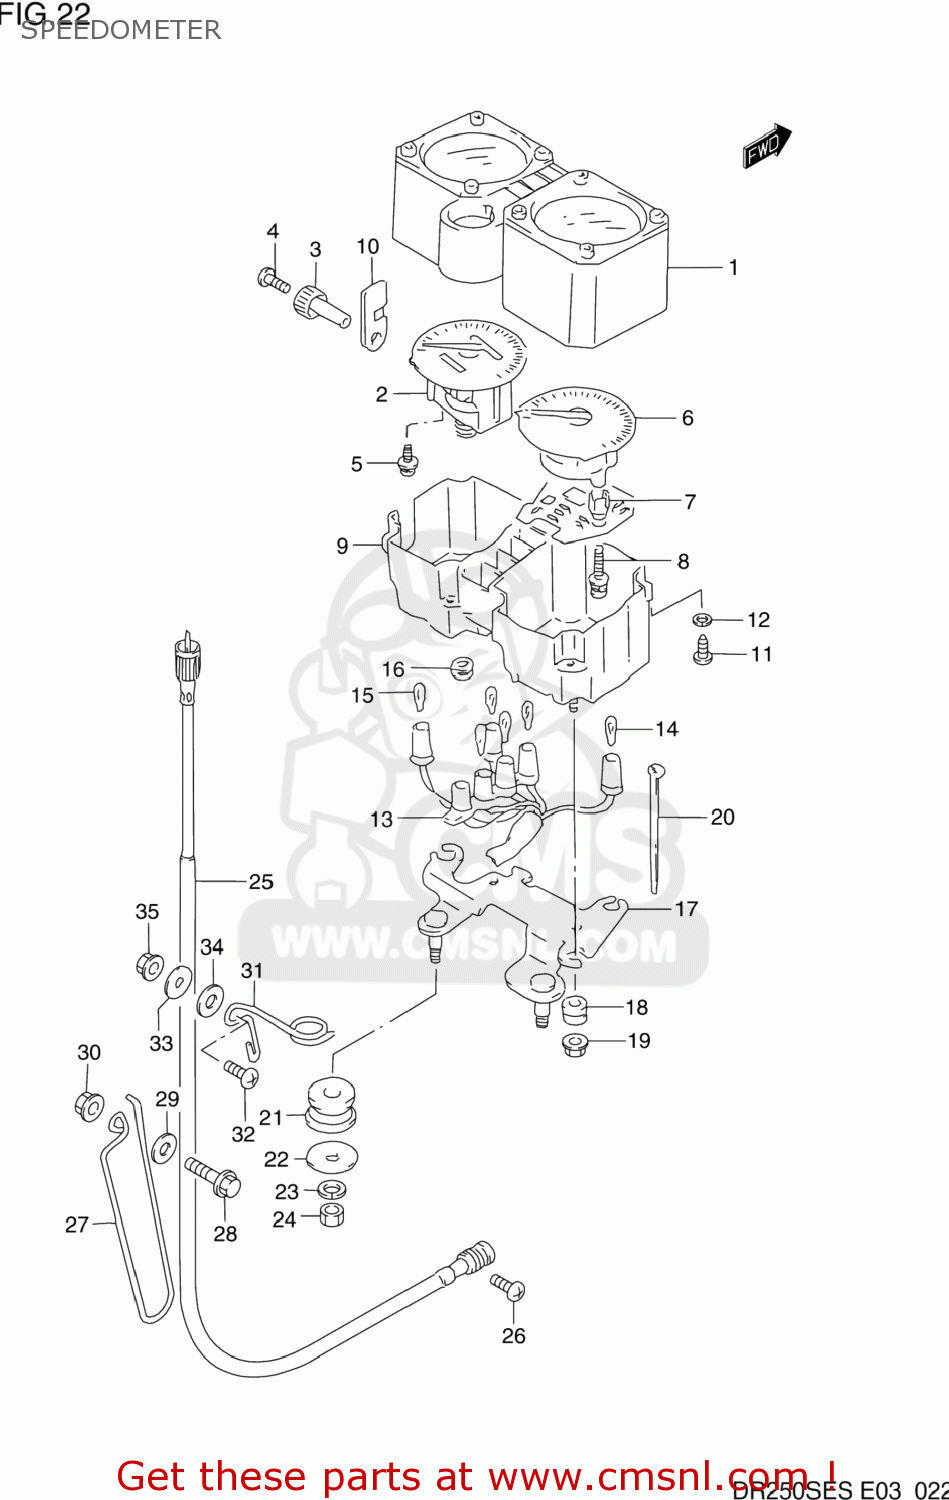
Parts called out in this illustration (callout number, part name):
1	HOOD,METER
2	SPEEDOMETER(MILE/KILO)
3	KNOB,TRIP
4	SCREW,TRIP KNOB
5	SCREW
6	TACHOMETER
7	SPACER
8	SCREW
9	CASE,METER
10	CUSHION,METER
11	SCREW
12	LOCK WASHER
13	SOCKET,METER
14	BULB(12V3W,WB371,T7)
15	BULB(12V1.7W,WB372,T7)
16	CAP
17	BRACKET
18	CUSHION,METER
19	NUT
20	CLAMP
21	CUSHION,METER BRACKET
22	WASHER (8.5X20X1.6)
23	LOCK WASHER
24	NUT
25	CABLE ASSEMBLY,SPEEDOMETER
26	SCREW
27	GUIDE,METER CABLE NO.2
28	BOLT
29	WASHER(6.5X20X1.6)
30	NUT
31	GUIDE,METER CABLE NO.3
32	SCREW
33	WASHER
34	WASHER
35	NUT
